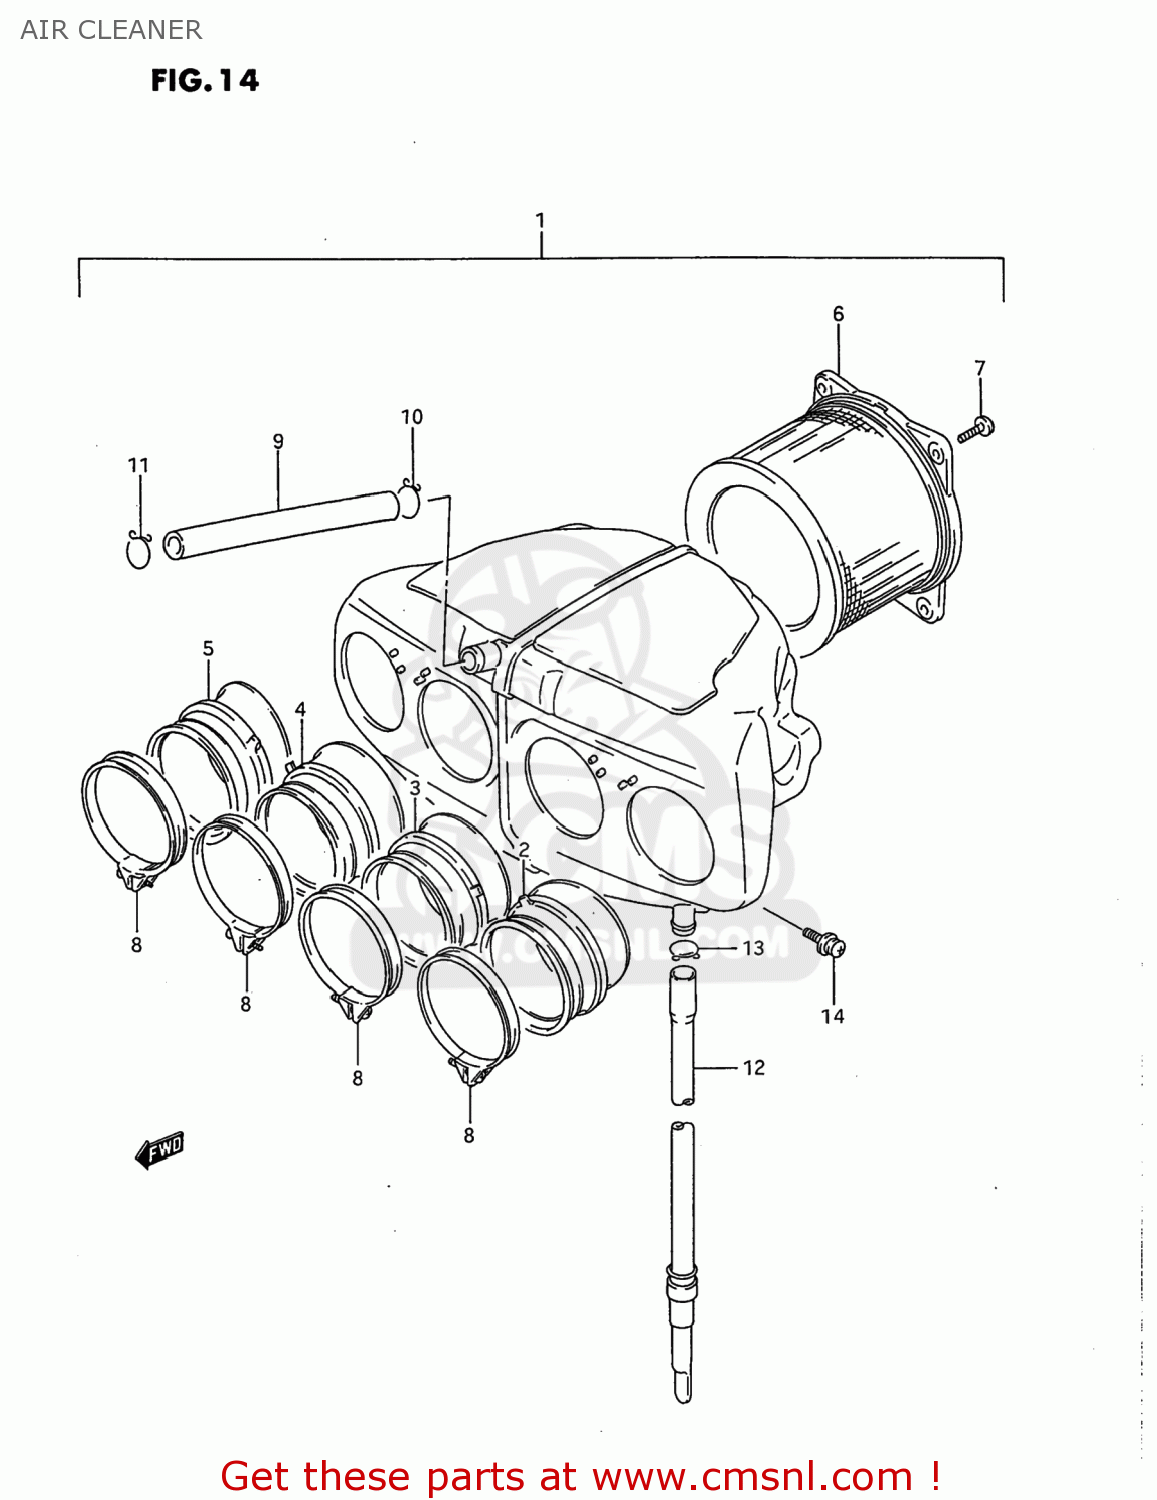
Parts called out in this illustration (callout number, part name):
1	CLEANER ASSY,AIR
2	TUBE,OUTLET,L
3	TUBE,OUTLET ML
4	TUBE,OUTLET MR
5	TUBE,OUTLET,R
6	FILTER ASSY
7	SCREW 5X12
8	CLAMP
9	TUBE,BREATHER
10	CLIP
11	CLIP
12	TUBE,DRAIN
13	CLIP
14	SCREW
